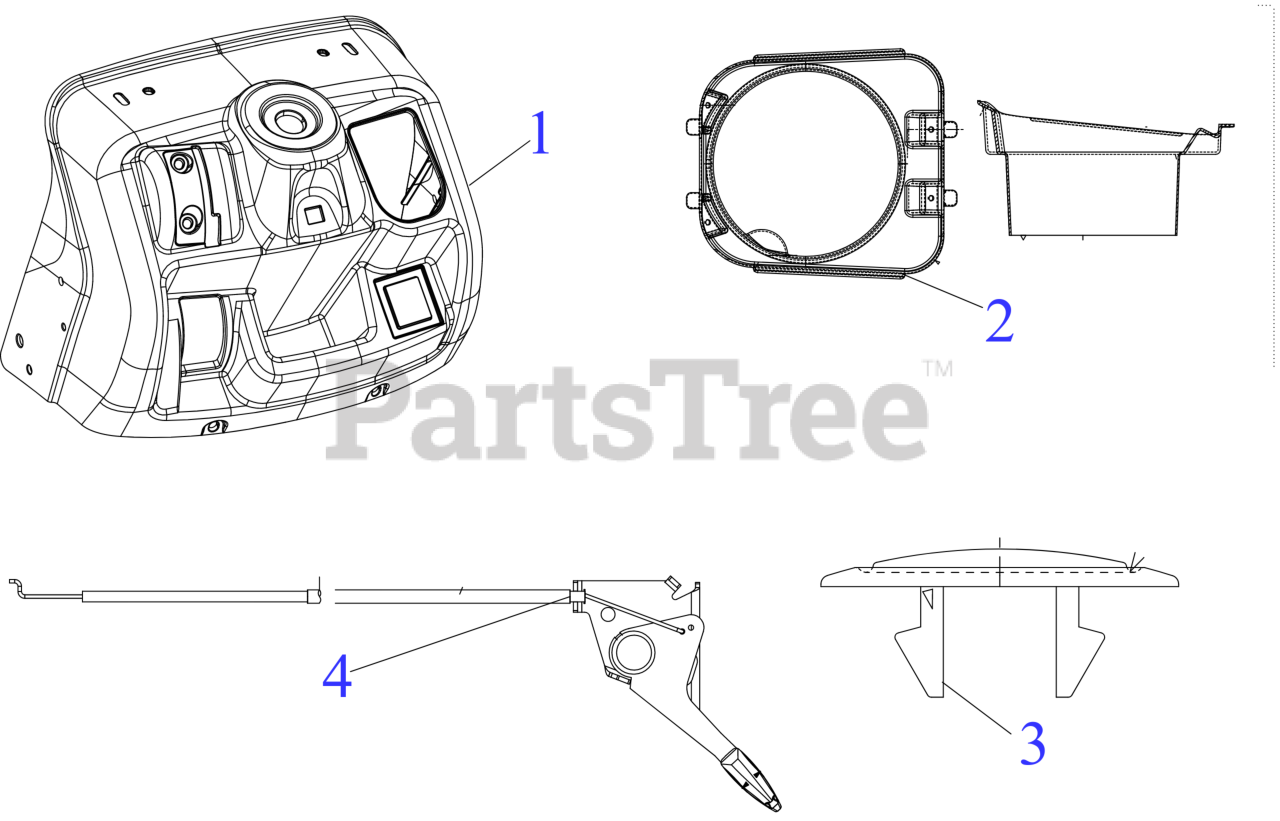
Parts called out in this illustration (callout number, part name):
1	UPPER DASH
2	HOOD PLENUM
3	CHOKE PLUG
4	THROTTLE CABLE 31" x 1.1
